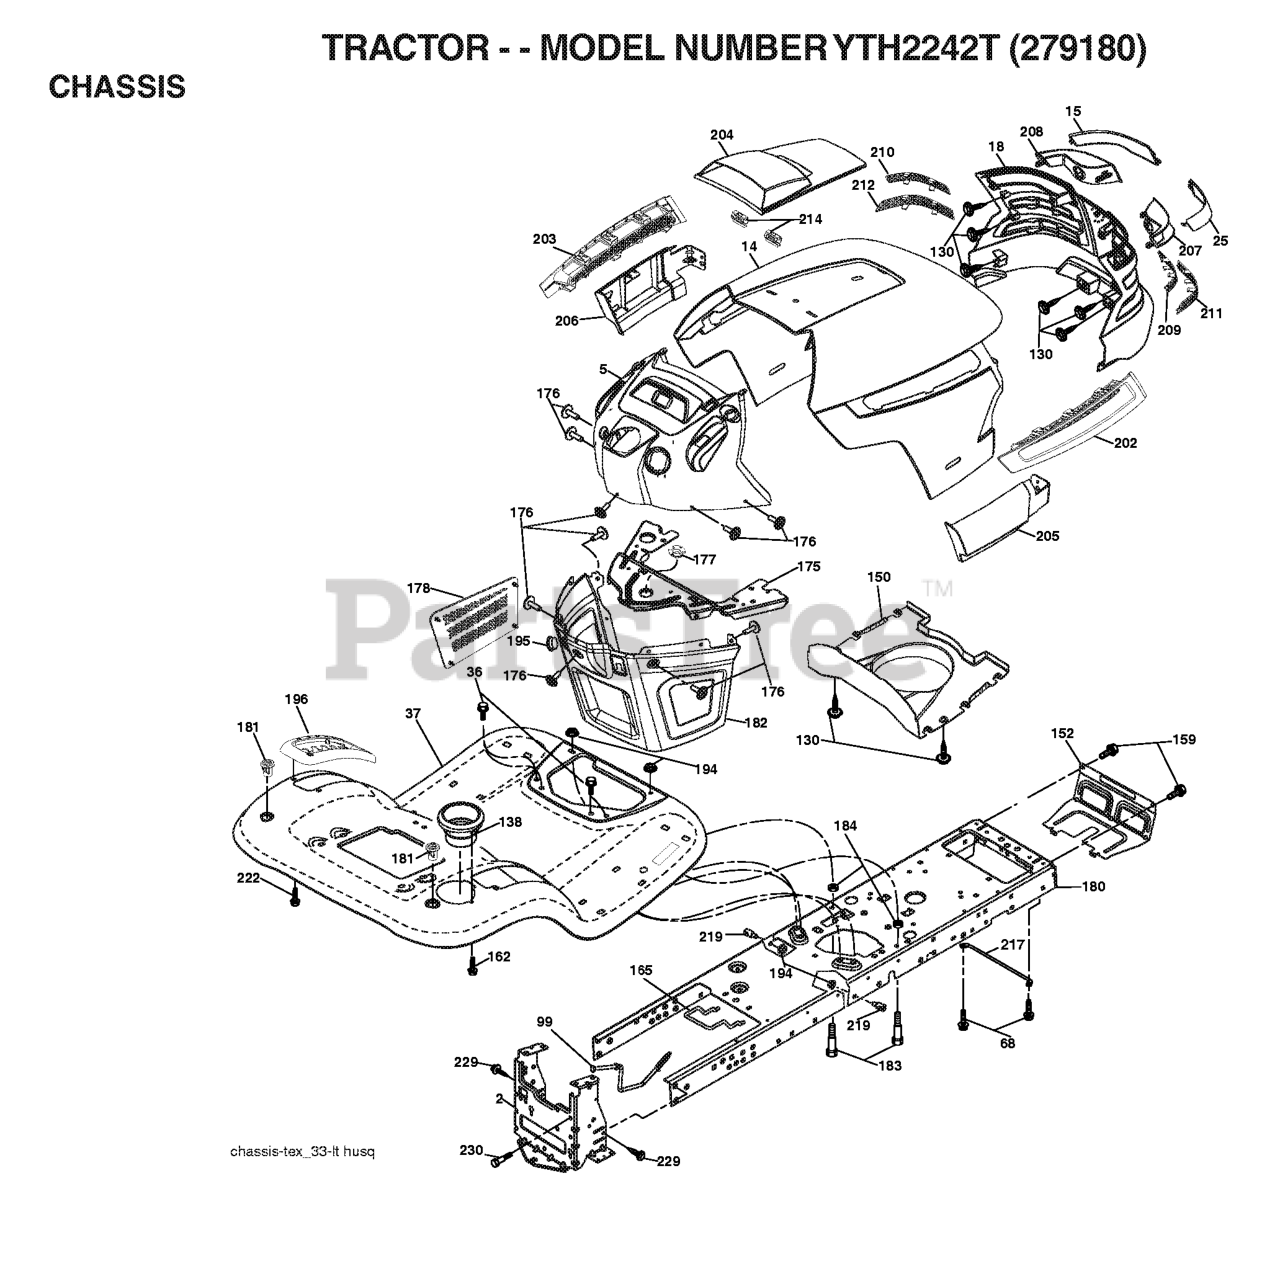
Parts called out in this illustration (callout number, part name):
2	DRAWBAR.1PC.NSTL
5	DASH.HUSQ.UPR.ELE.SVMD
14	HOOD.PNT.HUSQVARNA.GT.
15	LENS.LH.TEX.GT.HUSQ.CL
18	GRILLE.ASM.TEX.GT.HUSQ
25	LENS.RH.TEX.GT.HUSQ.CL
36	SCREW 5/16"
37	FEND/FTRST.PCH.CPH.NFW
68	Screw 5/16-18 x 1/2 Hex, Self Tapping 5/16-18 x 1/2
99	ROD.BYPASS.ASM.0510.HY
130	SCREW
138	CUPHOLDER.TL.TEX.418
150	AIR.DUCT.TEXGT.HUSQ.SV
152	SHIELD.BROWNING/DEBRIS
159	SCREW, 3/8-16X3/4
162	SCREW.HI-LO.CONSOLE
165	SUPPORT.TANK.REAR.WIRE
175	PLATE.CROSSMEMBER.HUSQ
176	SCREW.#10-24X5/8.RN.QU
177	BUSHING, STEERING
178	CARGO.ASM.NET.TXGT.W/C
180	CHASSIS.STAMPING.LT/GT
181	BUSHING.MNT.FEND.CRGO.
182	DASH.LOWER.COMMON.12V.
183	BOLT.5/16-18X1-1/4 FULL.THREAD
184	SPACER.FENDER
194	NUT LOCK HEX FLANGE 5/16-18
195	PLUG.HOLE.DASH.LOWER.12V.BLK
196	CONSOLE.ASM.DECK.LIFT.
202	VENT.SIDE.HOOD.HUSQ.RH.GREY
203	VENT.SIDE.HOOD.HUSQ.LH.GRAY
204	VENT.TOP.HOOD.HUSQVARN
205	SKIRT.HOOD.SIDE.HUSQ.RH.GREY
206	SKIRT.HOOD.SIDE.HUSQ.LH.GREY
207	BEZEL.RH.TEX.GT.HUSQ
208	BEZEL.LH.TEX.GT.HUSQ
209	INSERT.HEX.GRILL.HUSQ.GREY
210	INSERT.HEX.GRILL.HUSQ.
211	INSERT.HEX.GRILL.HUSQ.
212	INSERT.HEX.GRILL.HUSQ.
214	CLIP.RETAINER.TINNER.
217	ROD PIVOT CHASSIS/HOOD
219	STUD.FASTNER.W/ANTI-ROTATE
222	SCREW.1/4-20X5/8
229	SCREW 3/8-16X1
230	SHOULDER BOLT 5/16-18TT
